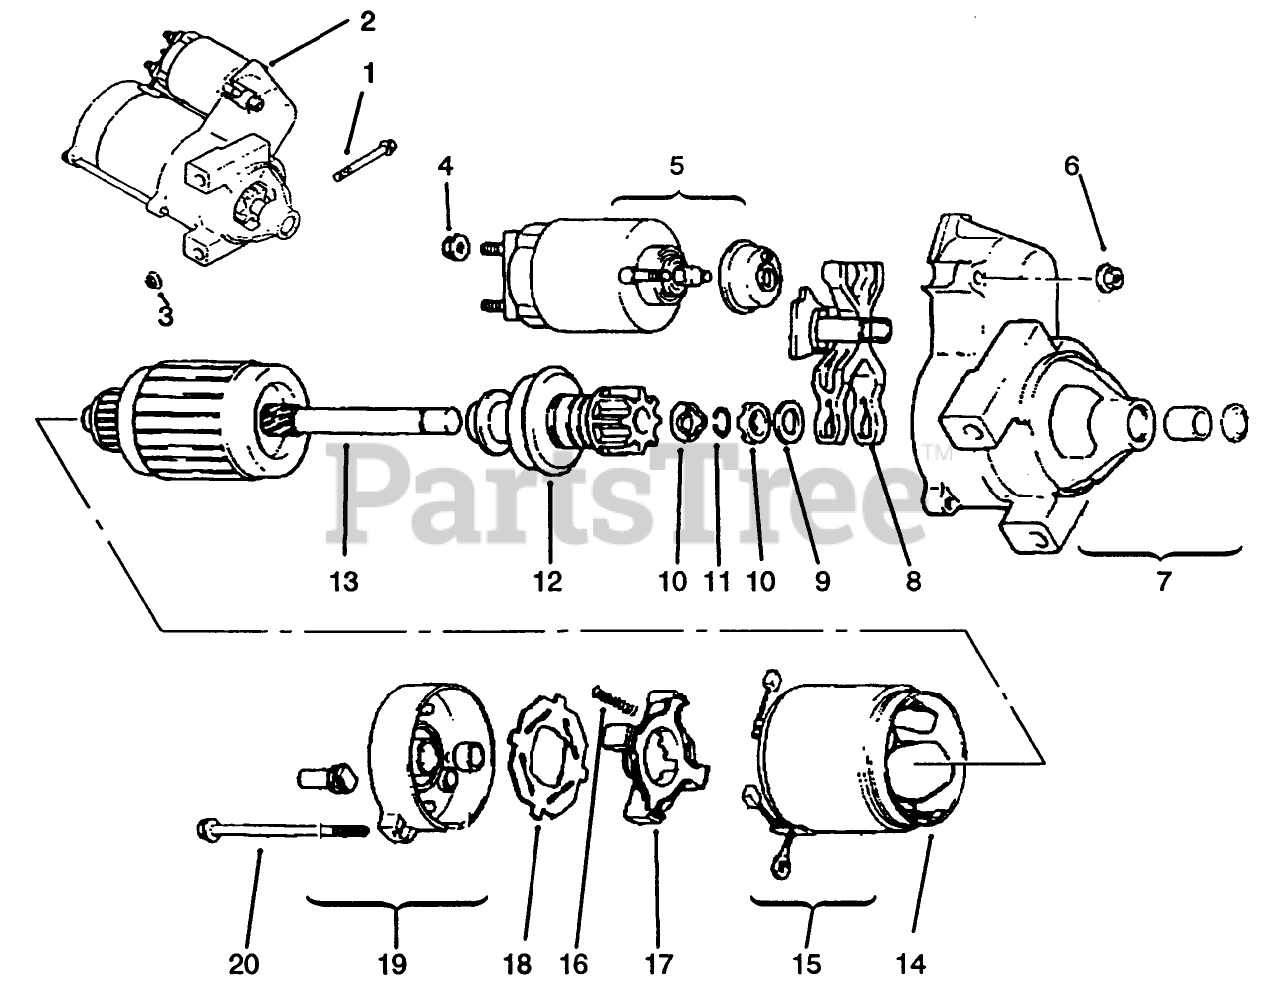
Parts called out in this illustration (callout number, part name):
1	Screw M8x1.25x80 (Only On: 72103, 72083)
2	Starter-Solenoid Shift (Incl. Ref. # 4-20)
4	Nut
5	Solenoid
6	Nut Starter
7	Cap-Drive End
8	Lever Starter Drive
9	Washer-Thrust (Only On: 72103, 72083)
10	Nut-Stop Collar
11	Ring-Retainer
12	Drive-Pinion
13	Armature-Starter
14	Frame
15	Kit-Brush (Incl. Ref. # 16)
16	Spring-Brush
17	Holder-Brush
18	Insulator
19	Cap-Commutator End
20	Bolt
